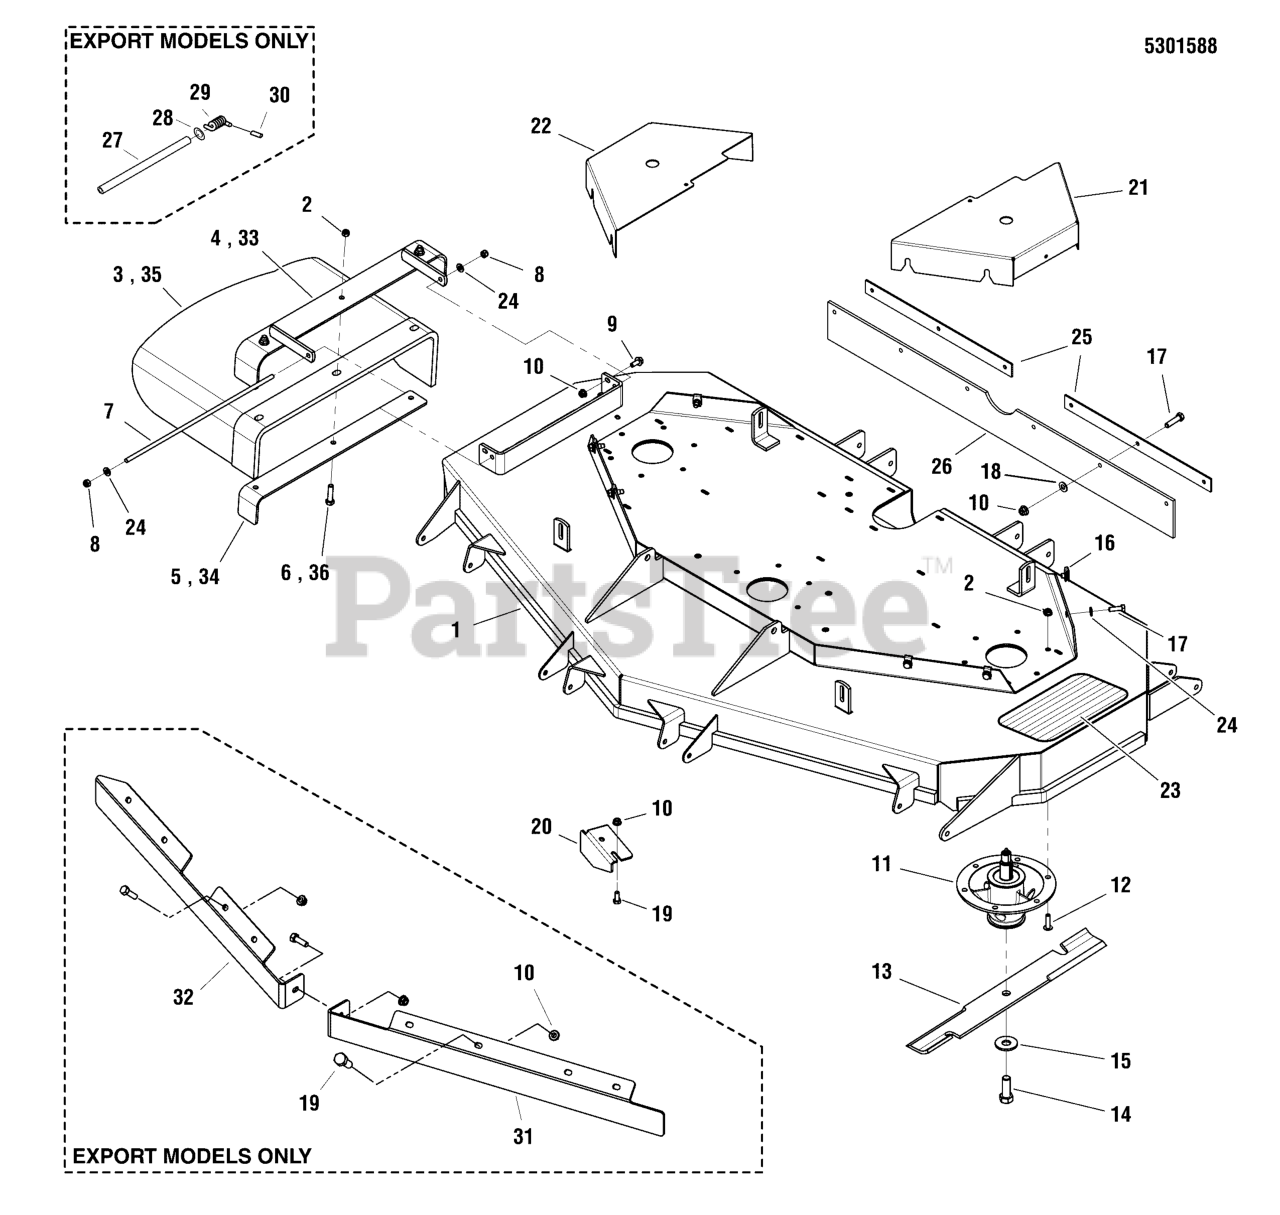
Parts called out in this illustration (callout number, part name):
1	DECK SHELL W/ DECALS, 61, S800X
2	NUT, 3/8-16 HEX NYLOCK FLANGE
3	CHUTE, DISCHARGE, BEND RUBBER (SV)
4	WELD, FRAME CHUTE, 61 - BLK
5	SUPPORT, DISCHARGE CHUTE, 61/72 - BLK
6	BOLT, 3/8-16 X 1-1/2" GD5 CZ
7	ROD MOUNT, CHUTE 61"
8	NUT, 5/16-24 HEX NYLON LOCK
9	BOLT, 5/16-18 X 3/4 GD5
10	NUT, 5/16-18 HEX NYLOCK FLANGE
11	SPINDLE ASSM, CAST IRON 8.0-6 BOLT
12	BOLT, 3/8-16 X 1, FLANGE, GD 5, CZ
13	BLADE, 21" (SET OF 3)
14	BOLT, 5/8-11 X 1-3/4 GD8
15	WASHER, BLADE BOLT, 9/16" F436, CZ
16	BODY CLIP, 5/16-18-7GA MATERIAL
17	BOLT, 5/16-18 X 1 GD5 YZ
18	5/16 PUSH-ON NUT RETAINER, STL, CZ
19	BOLT, 5/16-18 X 3/4, CARRIAGE
20	PLATE, DEFLECTOR - BLK
21	GUARD, 61, LH - OUTFRONT - RED
22	GUARD, 61, RH - OUTFRONT - RED
23	SAFETY WALK, 4.00 X 7.50
24	WASHER, 5/16" SAE
25	PLATE, SUPPORT, S800X - RED
26	FLAP, STRIPER, 61 DECK
27	TUBE, 1/2 X 3/8 X 10.75 BLACK POLY
28	WASHER, 5/16 FENDER
29	SPRING, TORSION
30	CAP, PROTECTOR, .120 ID
31	BAFFLE, BLOWOUT, 61 ICD, LH - BLK
32	BAFFLE, BLOWOUT, 61 ICD, RH - BLK
33	MOUNT
34	SUPPORT, DISCHARGE CHUTE - BLK
35	CHUTE, RUBBER DISCHARGE (5413499)
36	BOLT, 3/8-16 X 1-1/2, CARRIAGE, GD5, CZ
